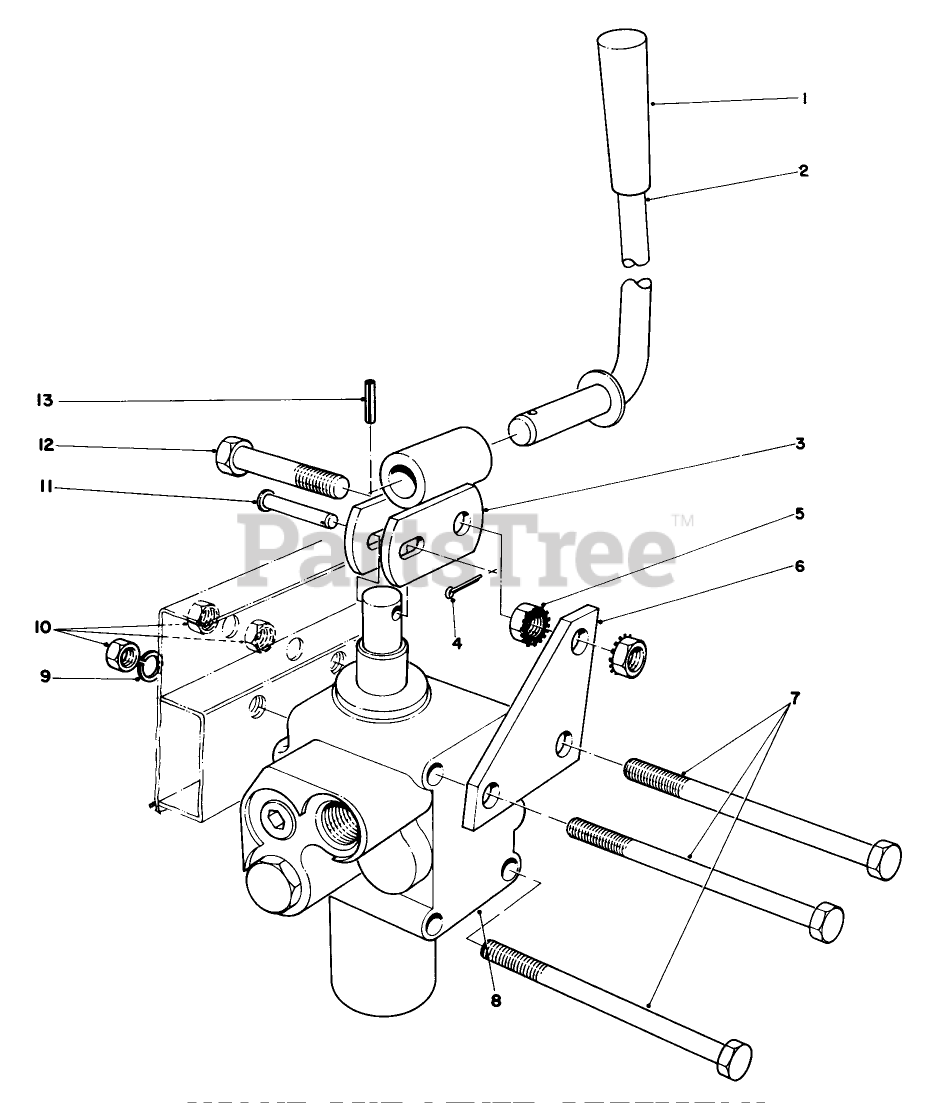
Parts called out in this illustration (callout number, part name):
1	KNOB-CONTROL
4	SCREW-HH
5	NUT-KEPS
7	SCREW-HH
9	SCREW-HH
10	NUT-HEX
11	PIN-CLEVIS
12	SCREW-HH
13	PIN-ROLL
